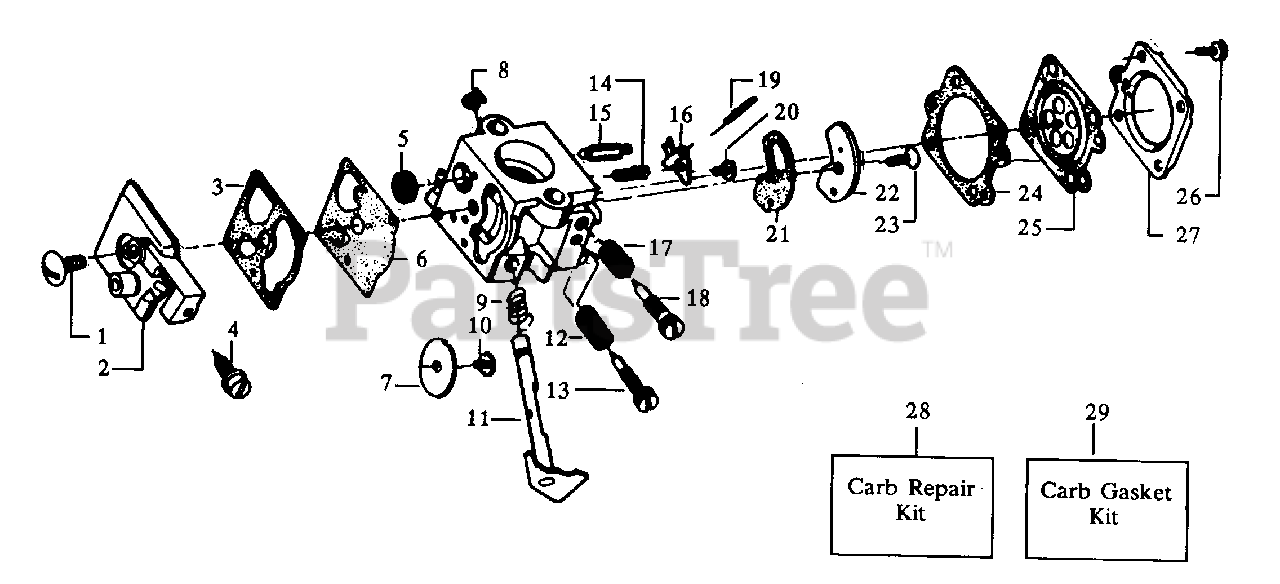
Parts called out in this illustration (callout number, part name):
1	Pump Cover Screw
2	Pump Cover Ass'y. (Inc. #4)
3	Pump Gasket
4	Idle Adjustment Screw
5	Inlet Screen
6	Diaphragm Pump
7	Throttle Valve
8	Throttle Shaft Clip
9	Throttle Return Spring
10	Throttle Valve Screw
11	Shaft Ass'y. - Throttle
12	Idle Needle Spring
13	Idle Needle
14	Metering Lever Spring
15	Inlet Needle Valve
16	Metering Lever
17	Hi Speed Needle Spring
18	Hi Speed Needle
19	Metering Lever Pin
20	Metering Lever Pin Screw
21	Circuit Plate Gasket
22	Circuit Plate
23	Circuit Plate Screw
24	Metering Diaphragm Gasket
25	Metering Diaphragm Ass'y.
26	Metering Cover & Throttle Shaft Clip Ass'y. Screw
27	Metering Diaphragm Cover
28	Carb Kwik Repair Kit
29	Carb. Gasket/Diaphragm Kit
